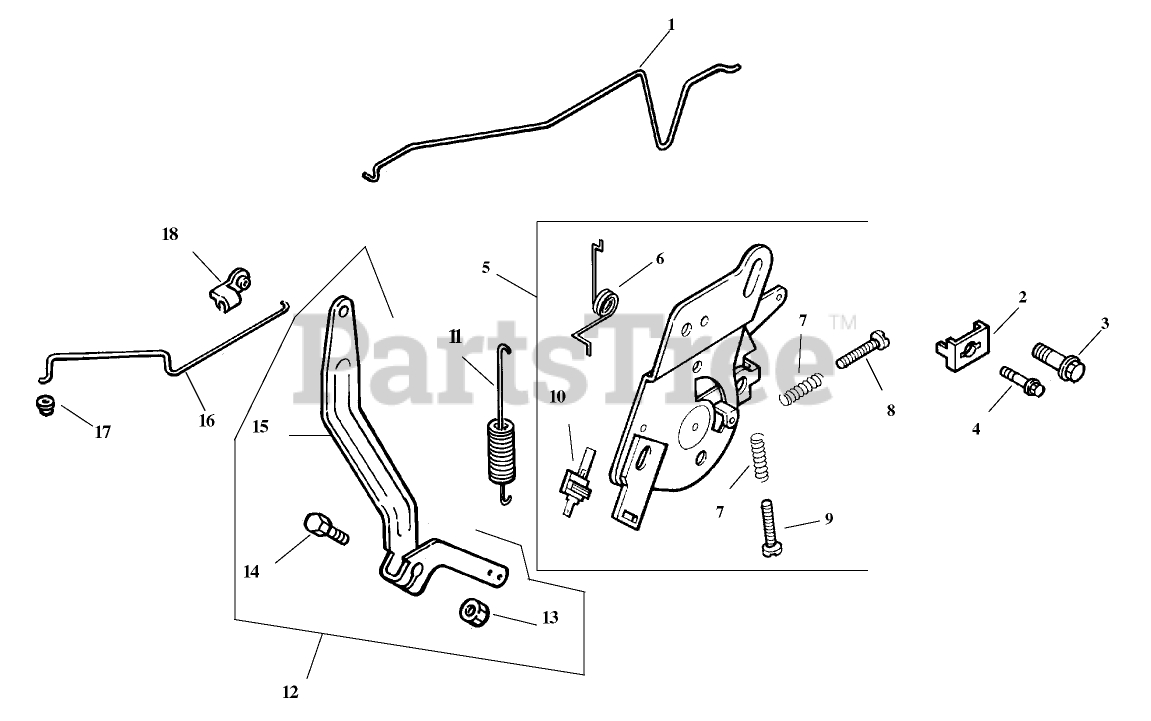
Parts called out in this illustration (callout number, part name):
1	Linkage-Choke
2	CLAMP-CABLE
3	Screw-Socket, 6 Lobed (Thread Forming, M6x1.0x20)
4	SCREW-FLANGE, THREAD FORMING (M5X0.8X16)
5	Speed Control ASM
6	Spring-Choke Return (Incl. 6-10)
7	Spring-Control, Speed
8	Screw-Pan Hd withLoctite
9	Screw-Pan Head (M4x0.7x20)
10	Terminal-Kill Switch
11	Spring-Governor
12	Kit-Governor Lever (Incl. 13-15)
13	Nut-Flange, Hex (1/4-20)
14	Bolt-Square Neck, Round Head (1/4-20x1)
15	Lever-Governor
16	Linkage-Throttle
17	BUSHING-LINKAGE, THROTTLE
18	BUSHING-RETAINING, LINKAGE
